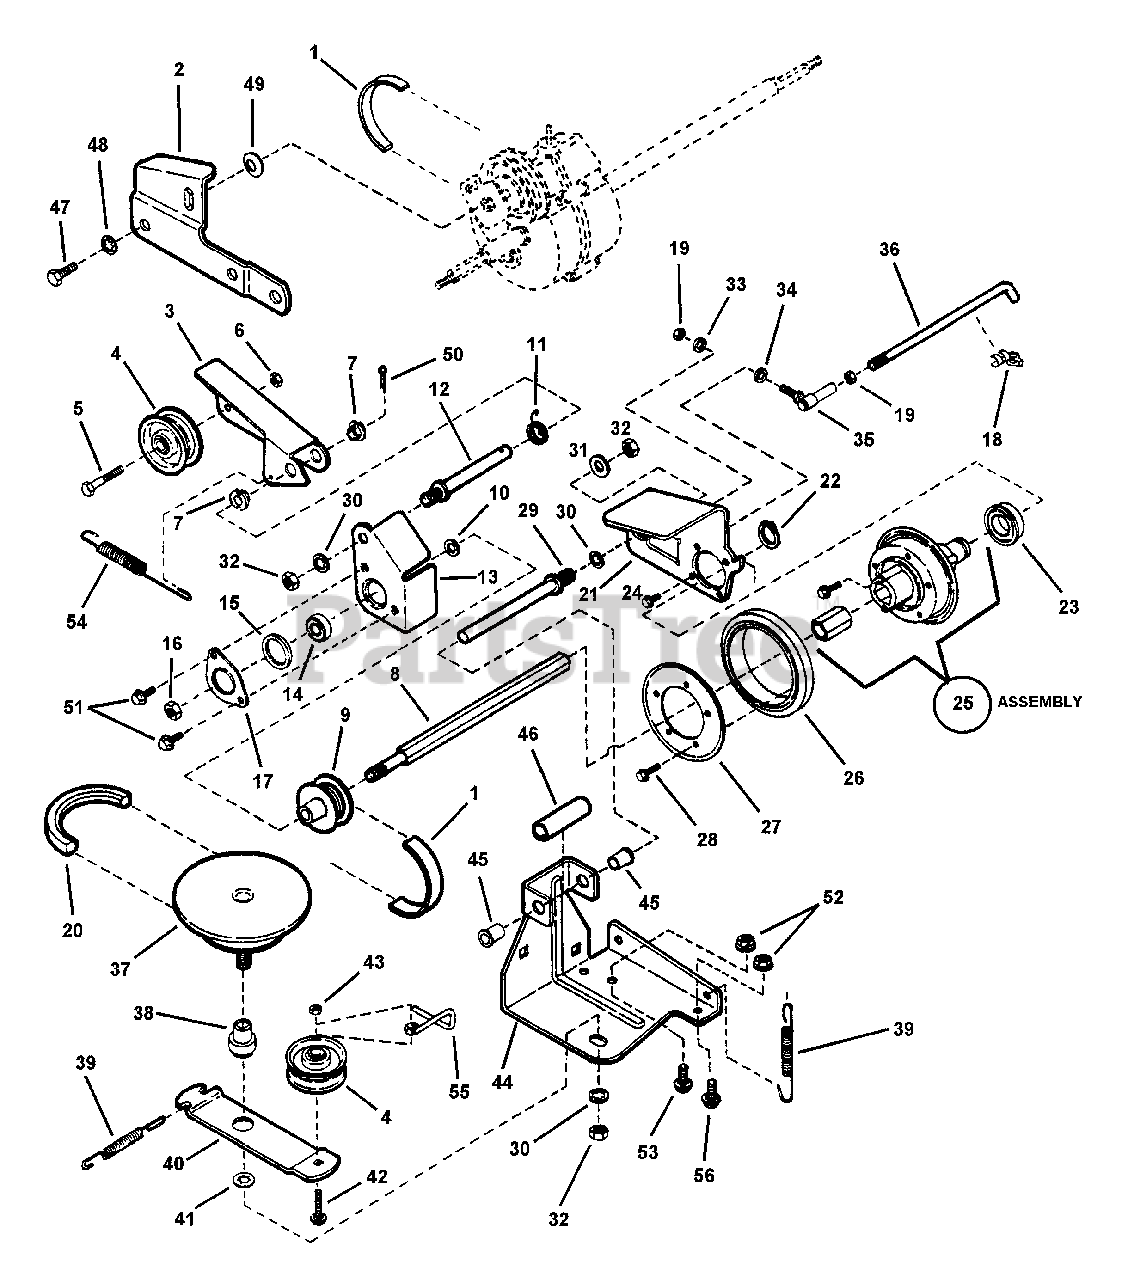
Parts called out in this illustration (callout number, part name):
1	BELT, Poly-Vee
2	LINK, Differential
3	ARM, Clutch Idler
4	PULLEY, Idler
5	SCREW, 1/4-28x1-3/8" Hex Head Cap, Grade 5
6	NUT, 1/4-28 Hex Top Lock
7	BUSHING, 3/8 I.D. Nylon
8	SHAFT, Hex
9	PULLEY, Poly-Vee
10	WASHER, 3/8" Flat
11	SPRING, Torsion
12	STUD (3/8-24 thread)
13	HOLDER, Bearing (Inner Half)
14	BEARING, Ball
15	O-RING
16	NUT, 3/8-24 Hex Center Lock, Grade 5
17	HOLDER, Bearing (Outer Half)
18	CLIP, 1/4 Right Arc (Transfer Rod)
19	NUT, 1/4-28 Hex, Grade 5
20	BELT, Engine Drive
21	PLATE, Thrust
22	RING, 3/4" External Retaining
23	BEARING, Ball
24	SCREW, #10-32x1/4" Self-Tapping Machine
25	ASSEMBLY, Hub (Includes 7011108 Bushing & 7090913 Screws)
26	RING, Driven
27	PLATE, Ring Retaining
28	SCREW, #10-24 x 1/2" Hex Washer Self-Tap (Torx)
29	GUIDE, Thrust Plate (3/8-24 thread)
30	WASHER, 3/8" Internal Tooth Lock
31	WASHER, 3/8" Flat
32	NUT, 3/8-24 Hex, Grade B
33	WASHER, 1/4" Flat
34	WASHER, 1/4" Internal Tooth Lock
35	JOINT, Ball
36	LINK, Transfer
37	KIT, Drive Disc Assembly
38	BUSHING
39	SPRING (Wheel Drive & Idler)
40	ARM, Idler
41	RETAINER, 3/8" Bolt
42	BOLT, 1/4-20x1-3/8" Carriage, Grade 5
43	NUT, 1/4-20 Hex Center Lock, Grade 5
44	BRACKET, Deck
45	BUSHING, Flange
46	SPACER
47	SCREW, 5/16-18x1/2" Hex Head Cap, Grade 5
48	WASHER, 5/16" Internal Tooth Lock
49	WASHER, 7/16" Curved
50	PIN, 3/32x1/2" Cotter
51	SCREW, 1/4-20x1/2" Self-Tapping
52	NUT, 5/16-18 Hex Flange Lock, Grade 5
53	BOLT, 5/16-18 x 1/2" Short Neck Carriage, Grade 5
54	SPRING, Clutch
55	SCRAPER, Drive Pulley
56	BOLT, 5/16-18 X 5/8" Short Neck Carriage, Grade 5
